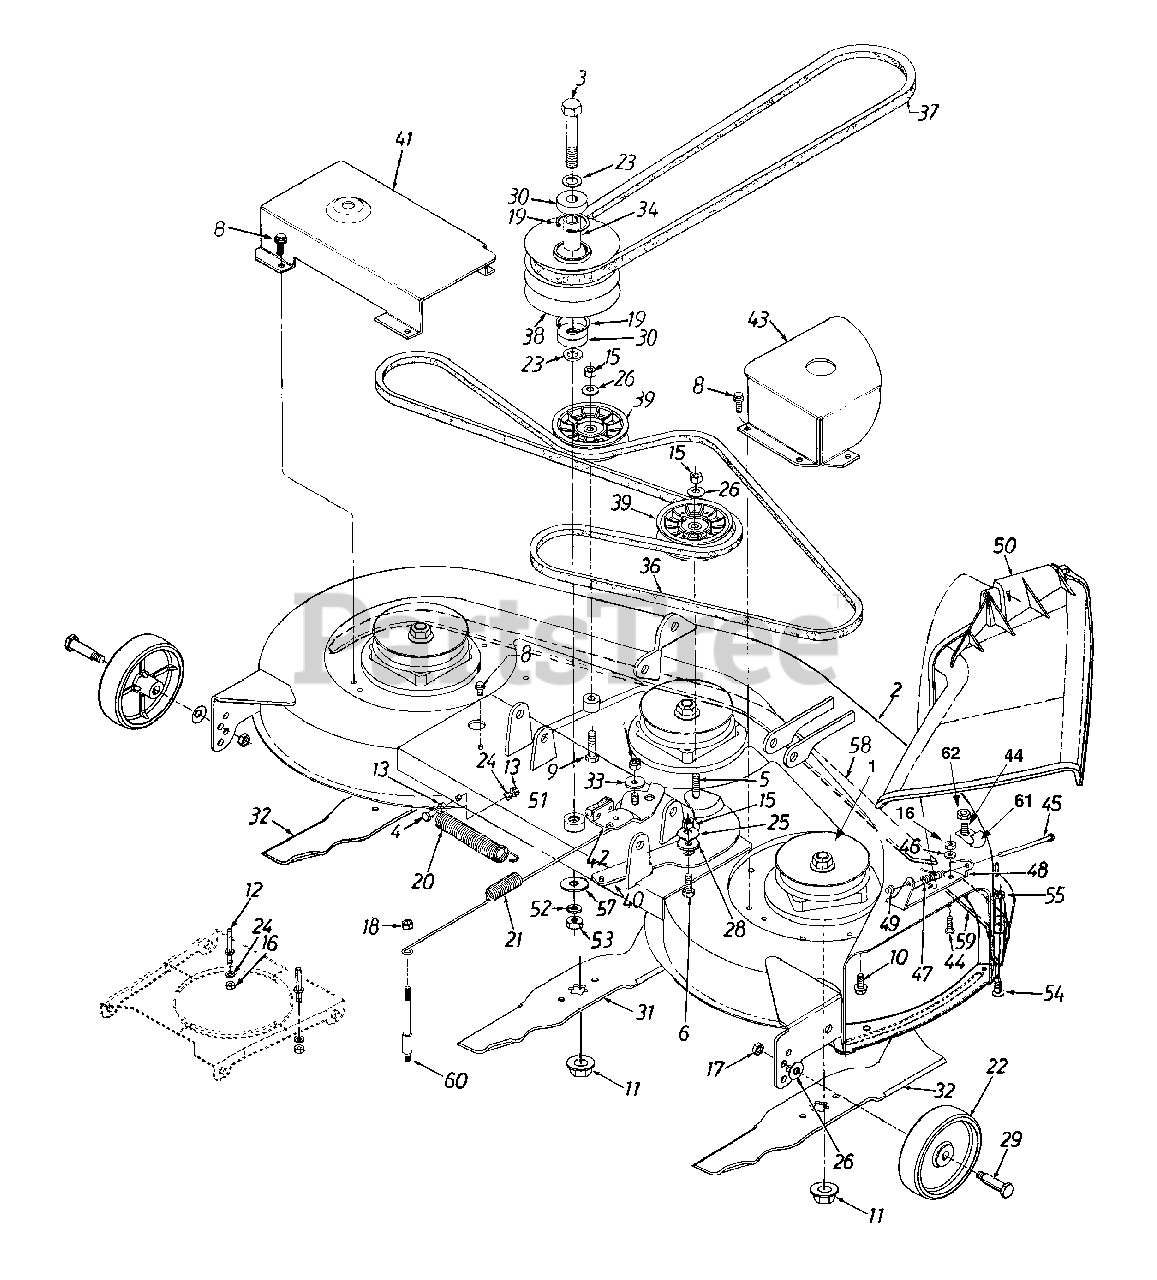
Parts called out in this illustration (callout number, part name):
1	Blade Spindle Assembly
4	Hex Bolt 1/4-28 x 1.25" Lg.
5	Hex Bolt 3/8-24 x 1.5" Lg.
6	Hex Bolt 3/8-24 x 1" Lg.
8	Hex Wash. Hd. TT-Tap Scr.1/4-20 x .5"
9	Hex Bolt 3/8-24 x 2" Lg.
10	Hex Flange Bolt 5/16-24 x .75" Lg.
11	Hex Flange Lock Nut 5/8-18 Thd.
12	Belt Guard Pin
13	Hex Nut 1/4-28 Thd.
15	Hex Nut 3/8-24 Thd.
16	Hex Nut 1/4-20 Thd. (Gr. 5)
17	Hex Top Jam Nut 3/8-16 Thd.
18	Hex Center Lock Nut 5/16-18 Thd.
19	Int. Snap Ring
20	Ext. Spring .88" O.D. x 6.17"
21	Ext. Spring .788" O.D. x 15.5"
22	Deck Wheel
23	Flat Washer .635" I.D. x 1" O.D. x.06"
24	Lock Washer 1/4" I.D.
25	BelLock Washer 3/8" x 1.125" x .062"
26	BelLock Washer 3/8" x .87" x .064"
28	Shoulder Spacer .625" I.D. x .169"
29	Shld. Bolt .498" x 1.525"
30	Ball Brg. .625" I.D. x 1.574" O.D. x .47"
31	Blade 14.88" Lg.
32	Blade 16.28" Lg.
33	Shoulder Spacer
34	Spacer .635" I.D. x .088" O.D.
36	V-Belt
37	V-Belt
38	Pulley Double Deck 5" O.D.
39	Flat Idler Pulley 3.5 O.D.
44	Hex Bolt 1/4-20 x .62" Lg.
45	Hinge Pin
46	BelLock Washer 1/4" I.D.
47	Torsion Spring
48	Hinge Mtg. Brkt.
49	Push Nut
50	Chute Assembly Comp.
51	Spacer .635" I.D. x 1" O.D.
52	Lock Washer 5/8" I.D.
53	Hex Nut 5/8-18 Thd.
54	Carriage Bolt 1/4-20 x .5" Lg.
55	Hex Sems Nut 1/4-20 Thd.
57	Flat Washer .635" I.D.
60	Return Spring Stud
61	Retainer Hook Bracket
62	Hex Lock Nut 1/4-20
